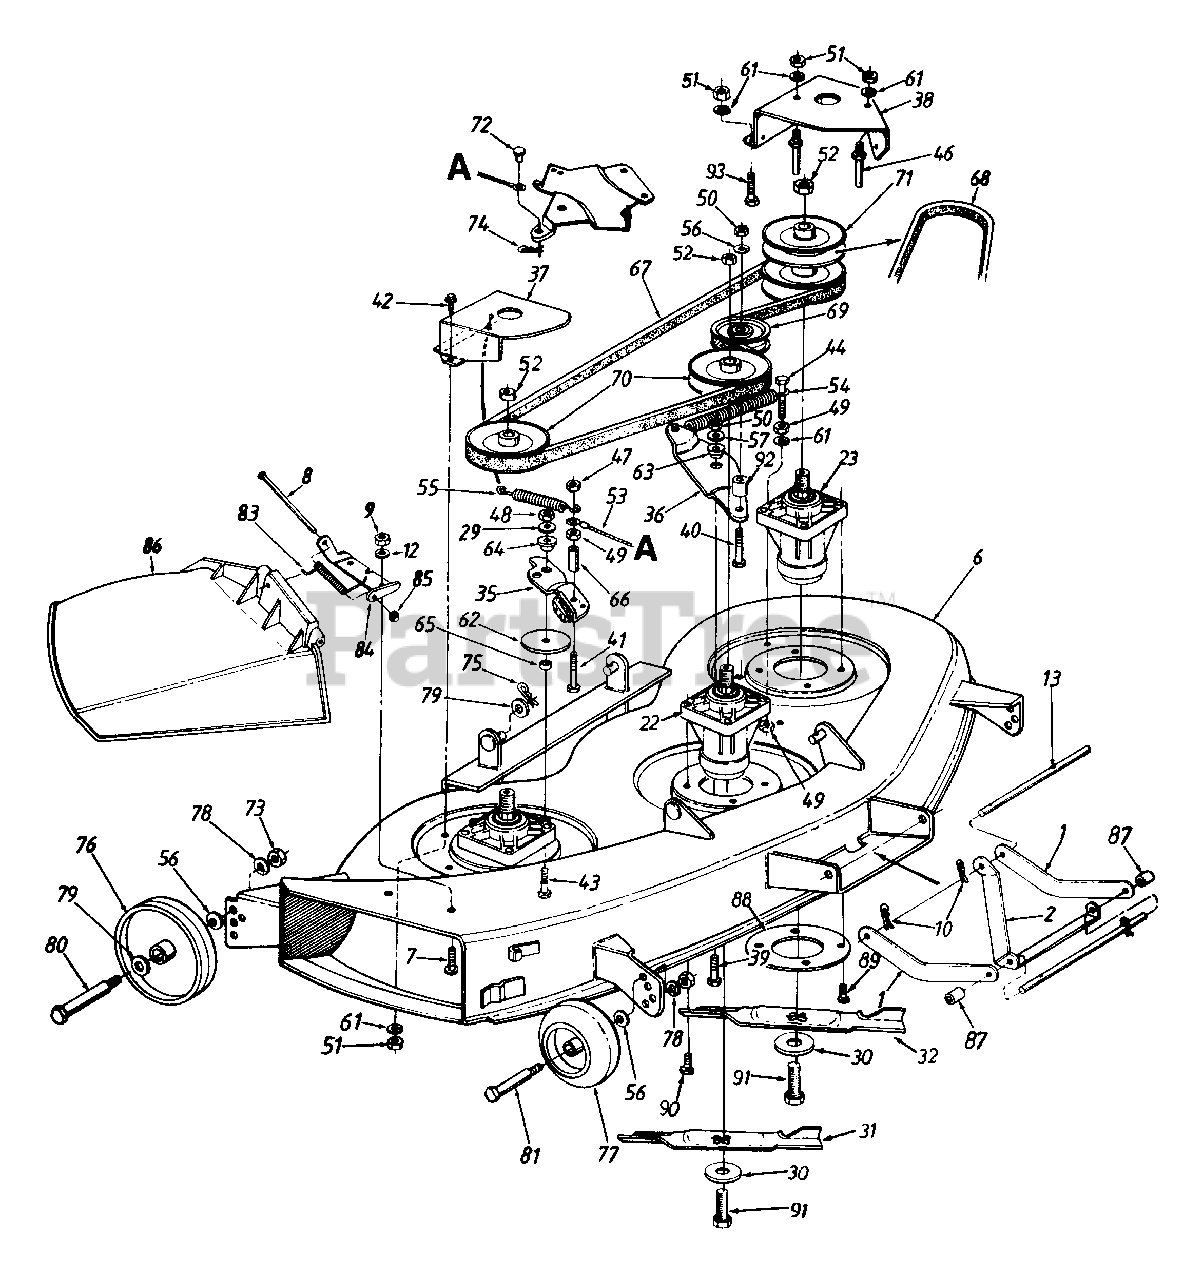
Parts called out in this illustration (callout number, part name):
8	Hinge Pin
9	Hex Nut 1/4-20 Thd.
12	Bell-Wash. 1/4" I.D.
13	Deck Connecting Rod
22	Spindle Ass'y.
23	Spindle Ass'y.
29	Lock Wash. 5/16" I.D.
30	Bell-Wash. .47" I.D. x 1.5"
31	High Lift Blade 14.88" Lg.
32	High Lift Blade 16.28" Lg.
35	Deck Brake Brkt. Ass'y.
36	Idler Bracket
39	Hex Bolt 3/8-24 x 1.0" Lg.
40	Hex Bolt 3/8-24 x 2" Lg.
41	Hex Bolt 1/4-28 x 1.75" Lg.
42	Hex Wash. Hd. Tap-Scr. 1/4-20 x .5" Lg.
43	Hex Bolt 5/16-24 x 1.5" Lg. (Grade 5)
44	Hex Bolt 1/4-28 x 1.5" Lg.
46	Belt Guard Pin 1/4" Dia.
47	Hex Cent. L-Nut 1/4-28 Thd.
48	Hex Nut 5/16-24 Thd.
49	Hex Nut 1/4-28 Thd.
50	Hex Nut 3/8-24 Thd.
51	Hex Nut 1/4-20 Thd.
52	Hex Flange L-Nut 5/16-18 Thd.
53	Brake Cable Ass'y.
54	Extension Spring 6.17" Lg.
55	Extension Spring 3.97" Lg.
56	Bell-Wash. .38" I.D. x .88" O.D.
57	Bell-Wash. .39" I.D. x 1.13" O.D.
61	L-Wash. 1/4" I.D.
62	Fl-Wash. 5/16" I.D. x 3" O.D.
63	Shld. Spacer .625" I.D.
64	Shld. Spacer
65	Spacer .34" I.D
66	Spacer .326" I.D.
67	V-Belt
68	V-Belt
69	Fl-Idler Pulley 3.5" O.D.
70	Pulley 5.0" Dia.
71	Double Pulley 5.0" Dia.
72	Clevis Pin 1/4" Dia. x .53" Lg.
73	Hex Nut 3/8-16 Thd.
74	Intern. Cotter Pin 5/16" Dia.
75	Intern. Cotter Pin 3/8 Dia.
76	Deck Wheel 5" Dia.
77	Deck Wheel w/Insert 5" Dia.
78	L-Wash. 3/8" I.D.
79	Fl-Wash. .531" I.D.
80	Shoulder Bolt .498" Dia. x 1.64" Lg.
81	Shoulder Bolt
83	Torsion Spring
84	Hinge Mtg. Brkt.
86	Chute Ass'y. Comp.
87	Spacer 5/8" I.D. x 7/8" O.D.
90	Hex Wash. Hd. Scr. 5/16-18 x .75" Lg.
91	Hex L-Bolt 7/16-20 x 1" Lg.
92	Spacer .38" I.D.
93	Hex Bolt 1/4-20 x .5" Lg.
